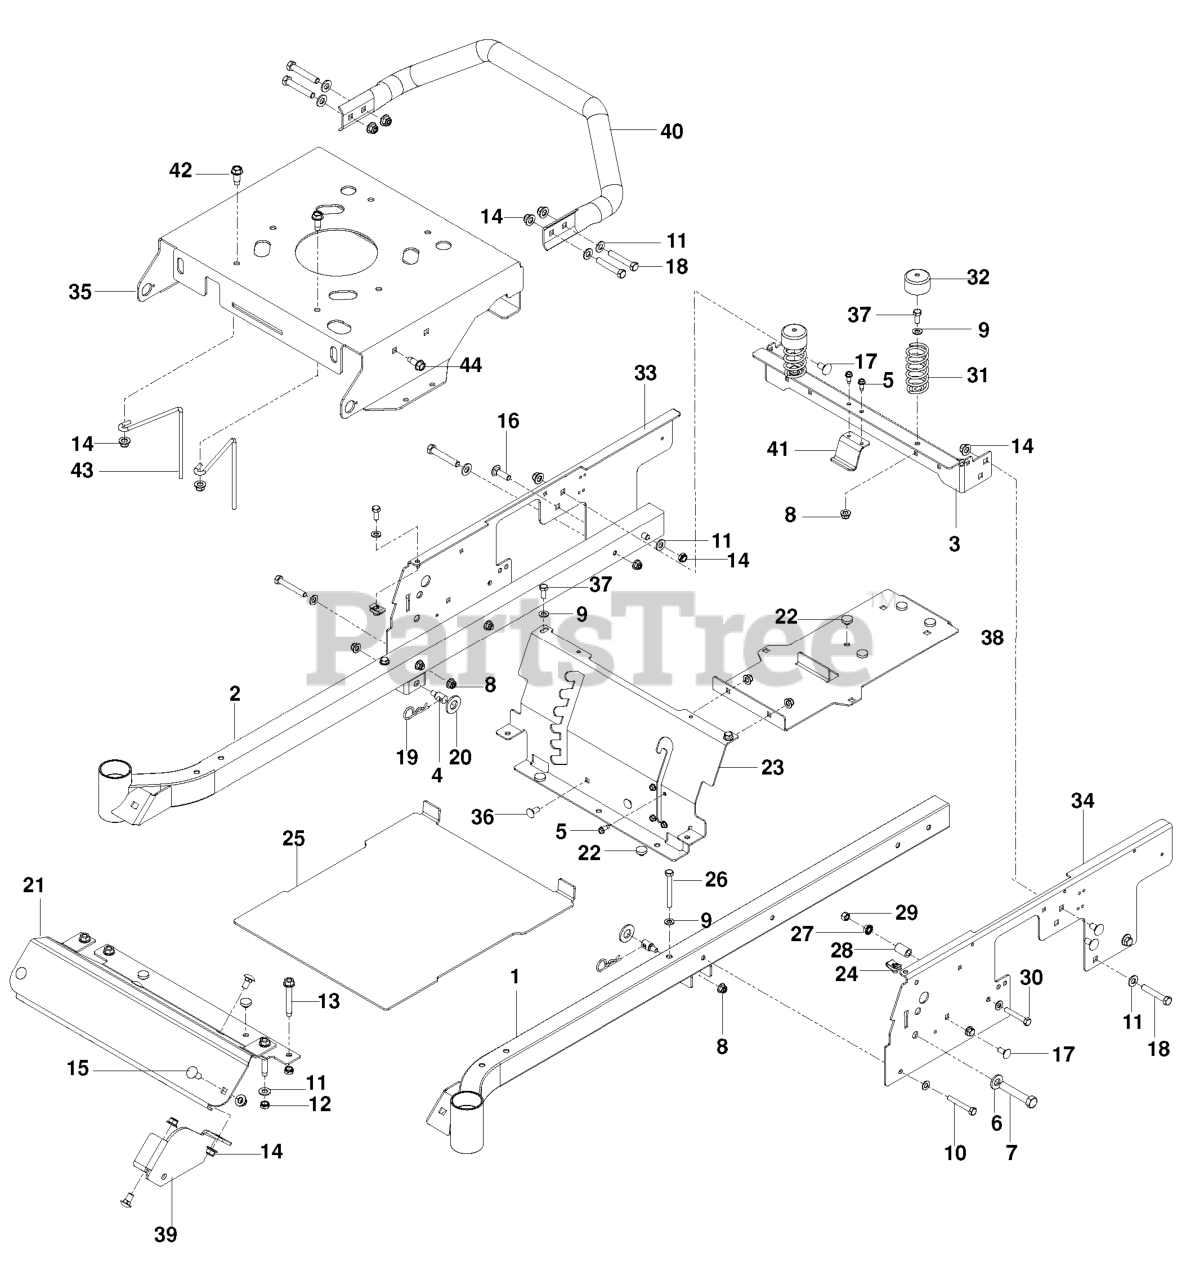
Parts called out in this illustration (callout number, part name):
1	FRAME TUBE, LH, ORG
2	FRAME TUBE, RH, ORG
3	SUPPORT, REAR SEAT, ORG
4	STUD.FASTNER.W/ANTI-ROTATE
5	SCREW 1/4 X 5/8
6	WASHER 1/2" FLAT
7	HCS 1/2C X 2 3/4
8	5/16-18 NYLOC FLANGE NUT
9	FLAT WASHER 5/16 SAE
11	WASHER 3/8 SAE FLAT
12	NUT HEX 3/8-16 NYLON, THIN
13	ENGINE BOLT, SPECIAL
14	NUT 3/8-16 HEX FLG NYLOC ZD
15	RHSNB 3/8C X 1
16	RHSNB 3/8-16 X 1-1/4
17	RHSNB 3/8-16 X 3/4 GR5 ZD
18	HCS 3/8C X 2 1/4
19	HAIRPIN #4
20	WASHER 5/8 FLAT
21	FOOT.REST.30/38.ORANGE
22	GROMMET, BUMPER
23	PANEL, SEAT SUPP. ORG
24	U-CLIP 5/16-18 NUT RETAINER
25	PLATE, FOOT W/DECALS, HUSQ
26	HCS 5/16C X 2-3/4
27	NUT 5/16C WHIZ
29	NUT 5/16 NYLOC
30	HCS 5/16-18X2
31	SEAT SPRING
32	SPRING CAP
33	PLATE.RH.SIDE.ORANGE
34	PLATE.LH.SIDE.ORANGE
35	PLATE, ENGINE, ORG
36	BOLT 5/16C X 3/4" CARRIAGE
37	HCS 5/16C X 3/4
38	SUPPORT, TANK/BATT, BLK
39	BRACKET, FRONT DECK, BLK
40	IMPACT BAR, ORG
41	HOLDING DEVICE, FUEL TANK, BLK
42	BOLT 3/8-16 X 1.0
43	BELT GUIDE
